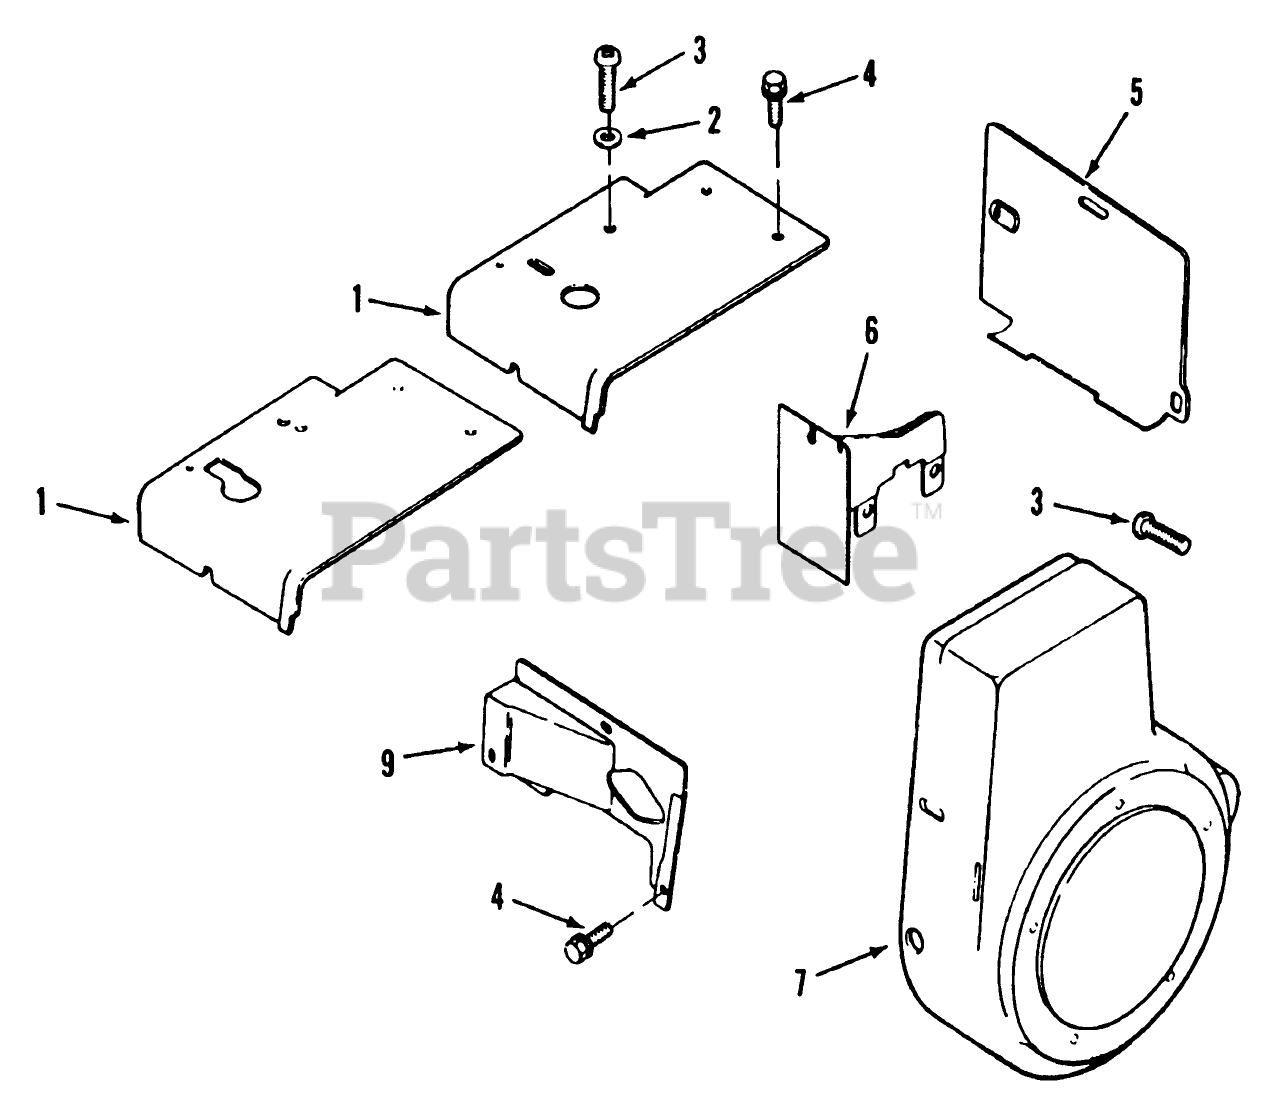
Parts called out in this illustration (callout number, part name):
1	KOHLER 47-063-09
2	KOHLER X-25-53
3	KOHLER 47-086-08
4	KOHLER 52-086-11
5	KOHLER 47-063-10
6	KOHLER 47-063-07
7	KOHLER 47-027-42
9	KOHLER 47-063-06
